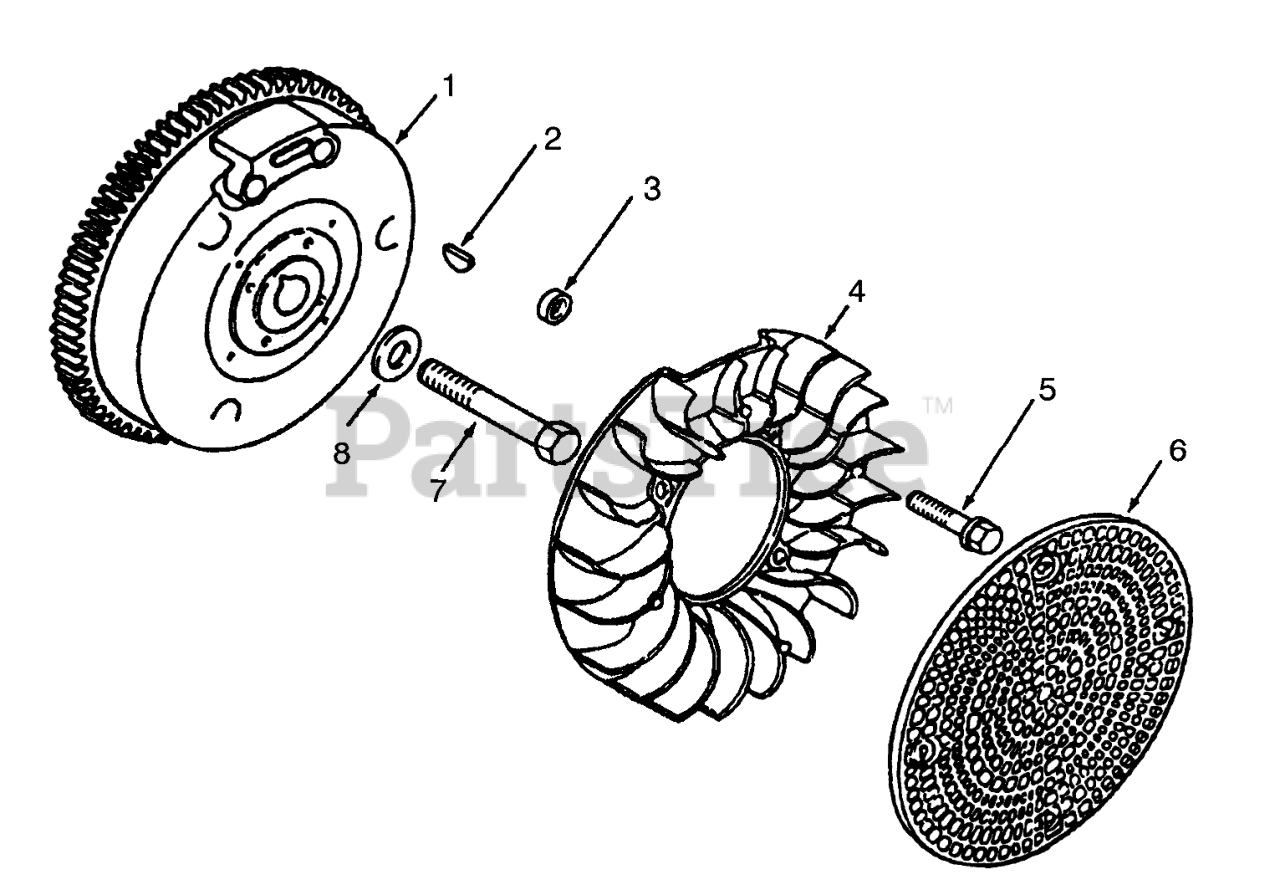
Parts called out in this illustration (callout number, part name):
1	Flywheel
2	Key-Woodruff
3	Spacer
5	Screw-Hex. Hd.
6	Screen
7	Screw
8	Washer
